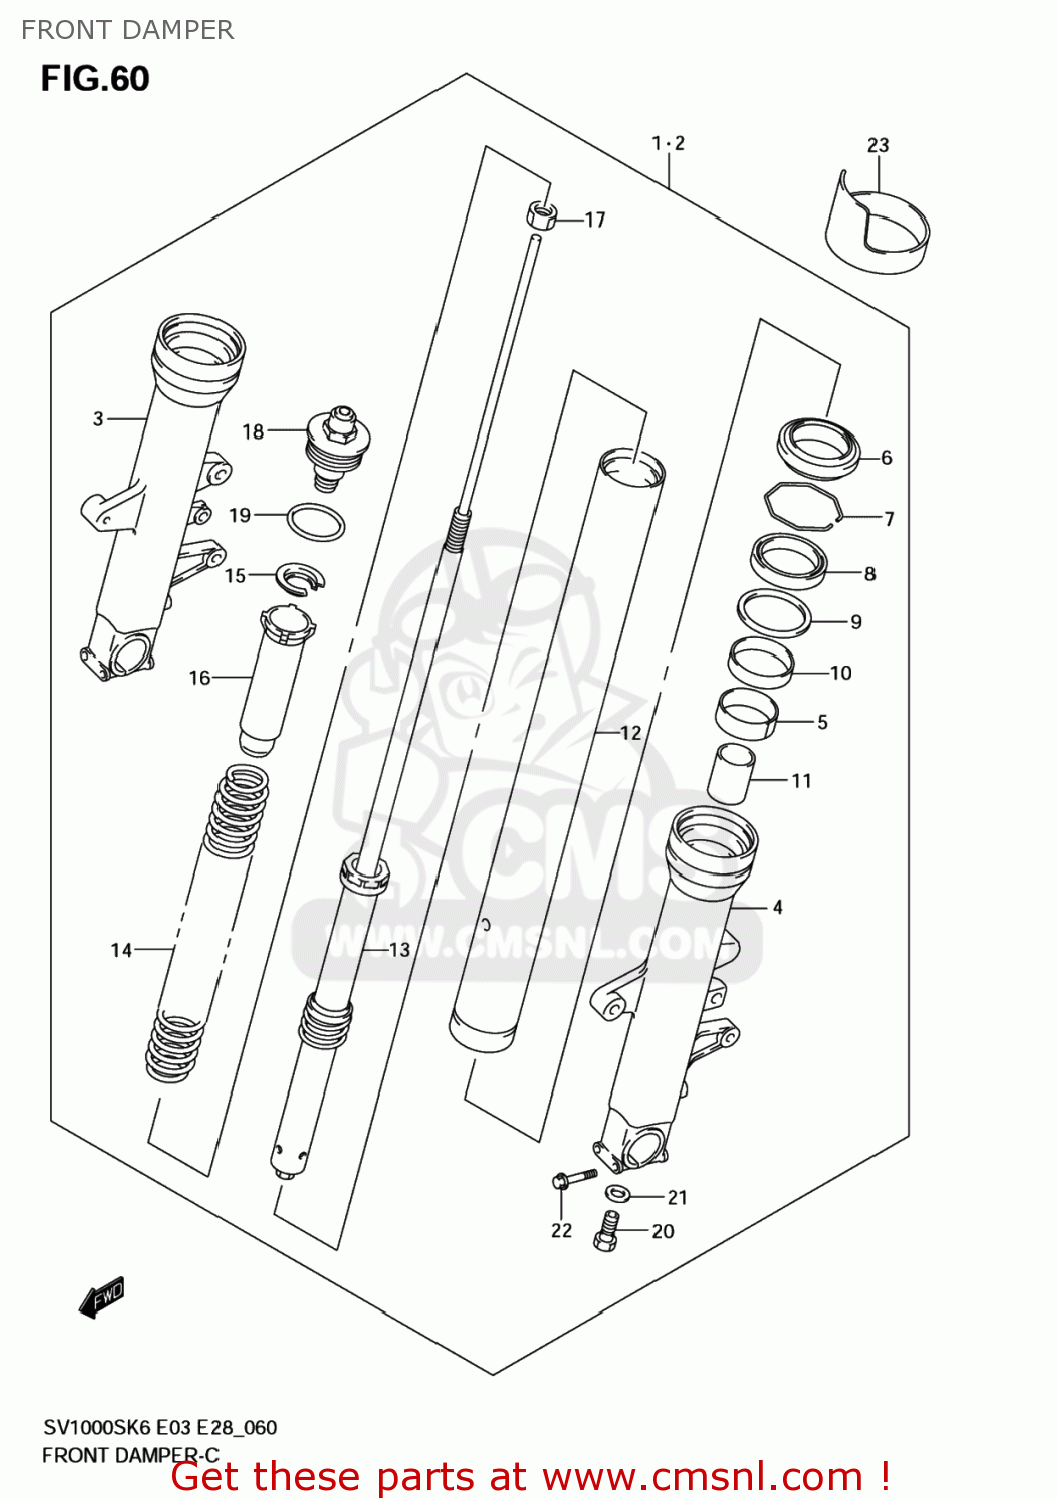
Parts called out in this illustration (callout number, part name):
1	DAMPER ASSY,FR FORK,R
2	DAMPER ASSY,FR FORK,L
3	TUBE,OUTER,R
4	TUBE,OUTER,L
5	BUSH,SLIDE
6	SEAL,DUST
7	RING,STOPPER
8	SEAL,OIL
9	WASHER
10	BUSH,GUIDE
11	PIECE,OIL LOCK
12	TUBE,INNER
13	CYLINDER
14	SPRING,FR
15	GUIDE,SPRING
16	SPACER
17	NUT
18	CAP,FORK
19	O RING
20	BOLT
21	GASKET (NAS)
22	BOLT
23	PROTECTOR
